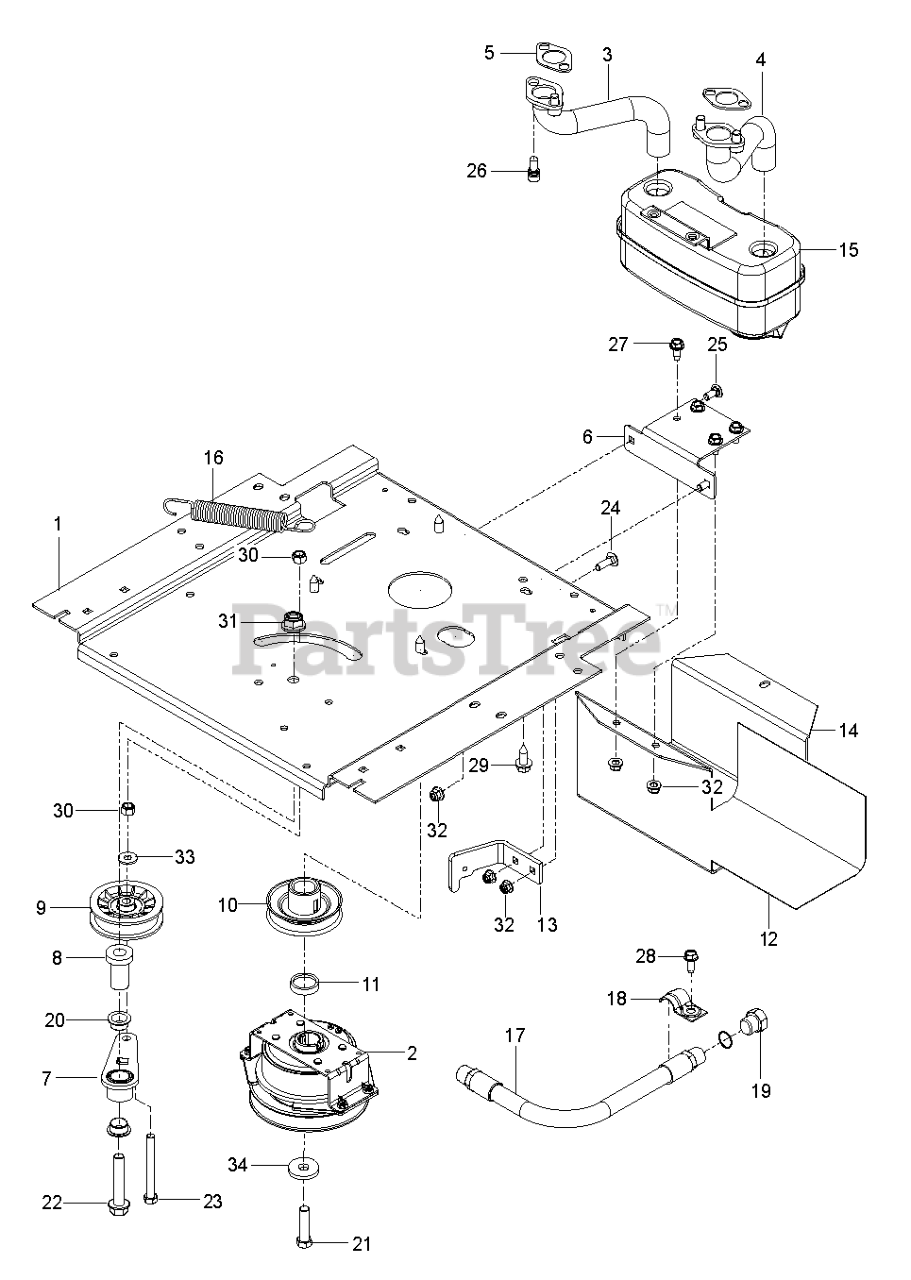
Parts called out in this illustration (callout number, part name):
1	PLATE ENGINE; RZ, 23IN BLACK
2	CLUTCH.OGURA.5.0PD.GT1.5A-EH07
3	PIPE.EXHAUST.RH.CV18/20
4	PIPE.EXHAUST.LH.CV18/20
5	GASKET.EXHAUST.KOHL.CV18-CV26
6	BRACKET MUFFLER MS431BLK
7	ARM IDLER
8	SPINDLE.IDLER
9	PULLEY, IDLER RAKE & ZTR
10	PULLEY.ENGINE
11	SPACER.SPACER.625 W/OGURA.LCC
12	HEAT SHIELD
13	CLUTCH.STOP.OGURA LCC.BLACK
14	GUARD.MUFFLER.WO.TOW.HITCHX431
15	MUFFLER ASM TWIN
16	SPRING, DECK DRIVE
17	HOSE.ASSEMBLY.OIL.DRAIN
19	BEARING.FLANGED.PLASTIC.3/4ID
20	BEARING.FLANGED.PLASTIC.3/4ID
21	CLUTCH BOLT7/16-20X2.5 GR524HR
22	BOLT.FLANGE.1/2-13 X 2.75.GRD5
23	HCS 3/8-16X3-1/2 TAPBLT GR5 ZD
24	RHSNB 5/16C X 1
25	BOLT 5/16C X 3/4" CARRIAGE
26	SCREW.SOCKET.HEAD.5/16-18
27	SCREW.THDROL.5/16-18X3/4.TTY
28	SCR 1/4-20X5/8 HEX SELF TAP ZD
29	SCREW 3/8-16X1
30	NUT 3/8-16 NYLOC
31	NUT, 1/2-13 HEX FLG NYLOC ZD
32	5/16-18 NYLOC FLANGE NUT
33	WASHER.5/16.FLAT.STE.STD.
